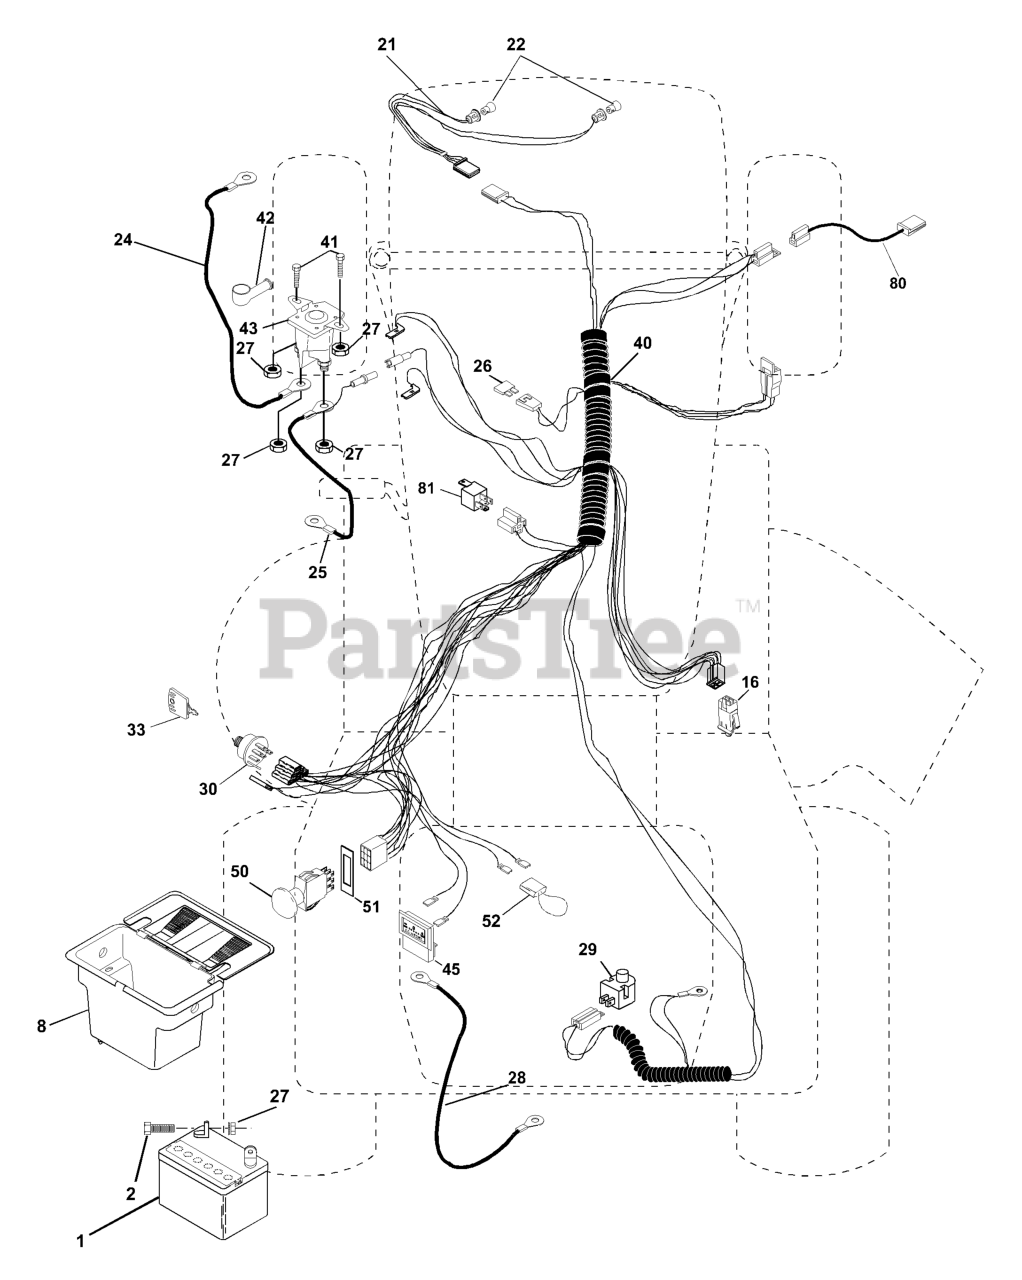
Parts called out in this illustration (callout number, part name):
1	BATTERY 12 VOLT 25 AMP
2	BOLT.HEX.1/4.X.3/4.DICHROMATE
8	CASE BATTERY MECH HINGE
16	SWITCH INTERLOCK
20	NUT
24	BATTERY CABLE GT
25	CABLE BATTERY
26	FUSE 15 AMP
27	NUT
28	CABLE T
29	PLUNGER SWITCH (COLOR:OLIVE)
30	SWITCH IGN
33	KEY MLD GEN DELTA
40	HARNESS, ELEC IGNITION
41	BOLT
42	TERMINAL COVER
43	SOLINOID
50	PTO SWITCH
51	FRAME RETAINING RING
52	WIRE PROTECTION LOOP
80	HARNESS, CLUTCH
81	RELAY.ASSY.T
